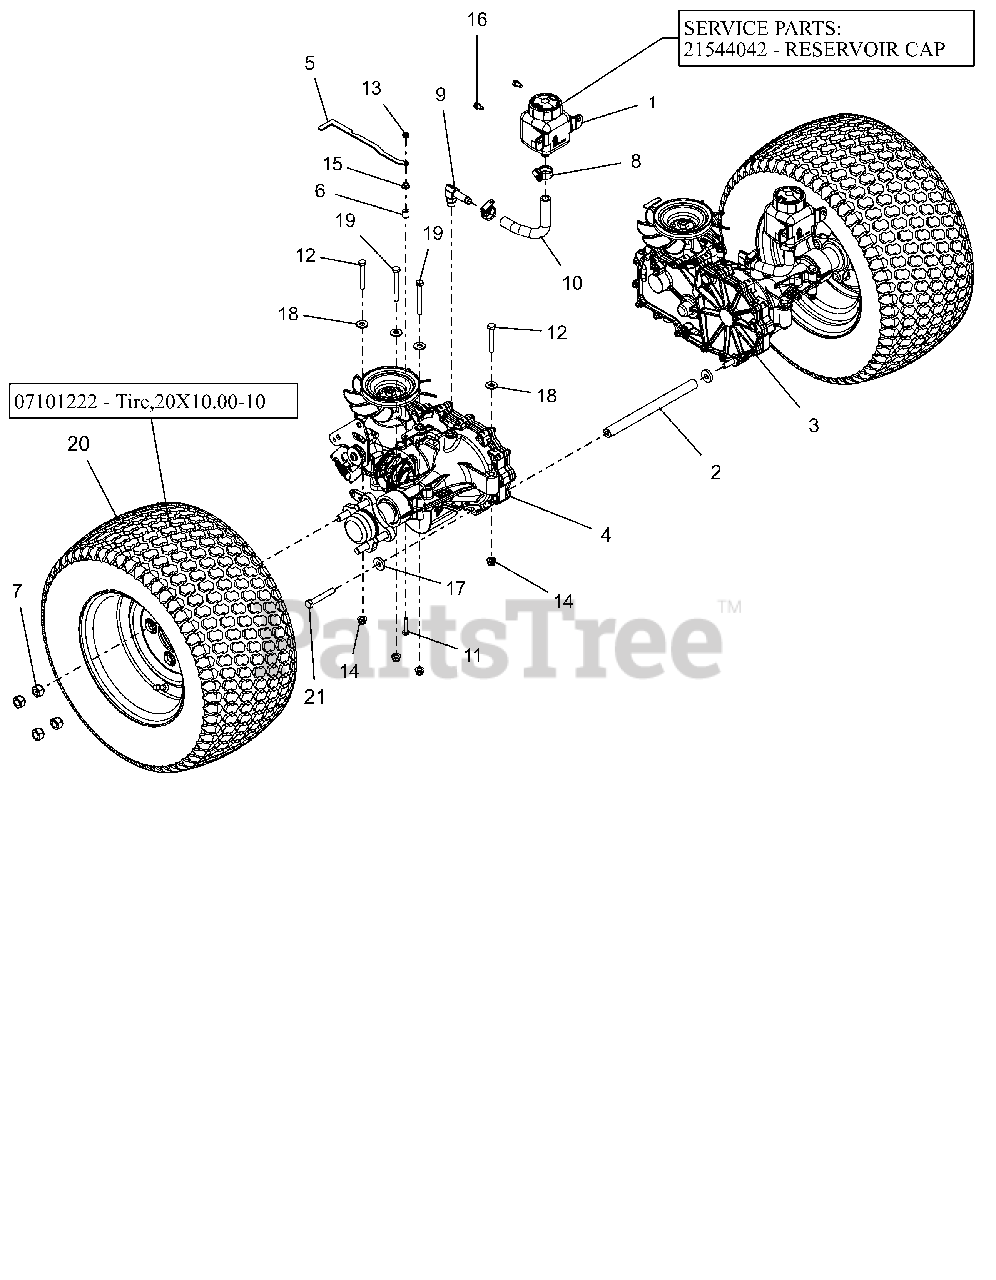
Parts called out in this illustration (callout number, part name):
1	TANK, EXPANSION
1	CAP, HYDRO RESERVOIR REPLAC.
2	ROD, TRANSAXLE BRACE 9.27
3	TRANSAXLE,ZT2800 LH
4	TRANSAXLE,ZT2800 RH
5	BRKT, DUMP VALVE
6	BSHG-SLV .265X.500X.500
7	WHEEL NUT .500-20 YZ
8	CLAMP,.88 DIA. HOSE
9	FITTING, HYD (90 DEG)
10	HOSE, FORMED LH XL
11	@BLT-HEX .25-20X1.25 GR5 YWZC
12	@BLT-HEX .31-18X2.25 GR5 YWZC
13	NUT-LK-CTR JAM .25-20 YWZC
14	@NUT-LK-NYL-FLG .31-18 YWZC
15	@NUT-SPNLK-FLG .25-20 YWZC
16	SCR-TAP .25-20X.50 HWH TR YWZ
17	WSHR-FL-STL .406X1.00X.188 YWZ
18	@WSHR-FL-STL.38X.875X.083 YWZC
19	@BLT-HEX .31-18X2.75 GR5 YWZC
20	ASM, WHL/TIRE 20X10.00-10
20	TIRE, 20X10.00-10 (OTR)
21	@BLT-HEX .38-16X2.50 GR5 YWZC
